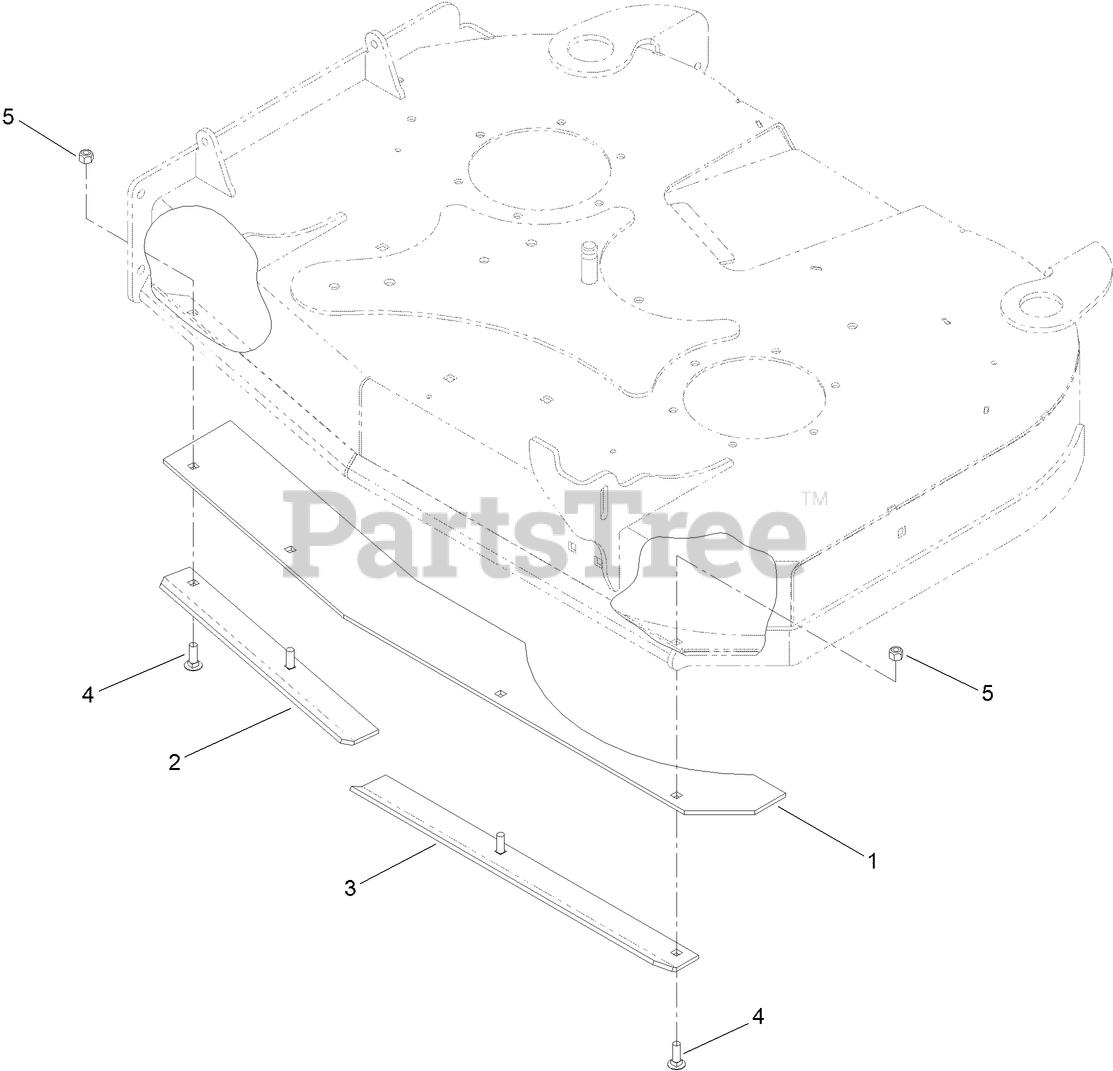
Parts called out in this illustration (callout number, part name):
1	SKIRT-RUBBER
2	BRACKET-SKIRT, RH
3	BRACKET-SKIRT, LH
4	BOLT-CARR
5	NUT-LOCK, NI
